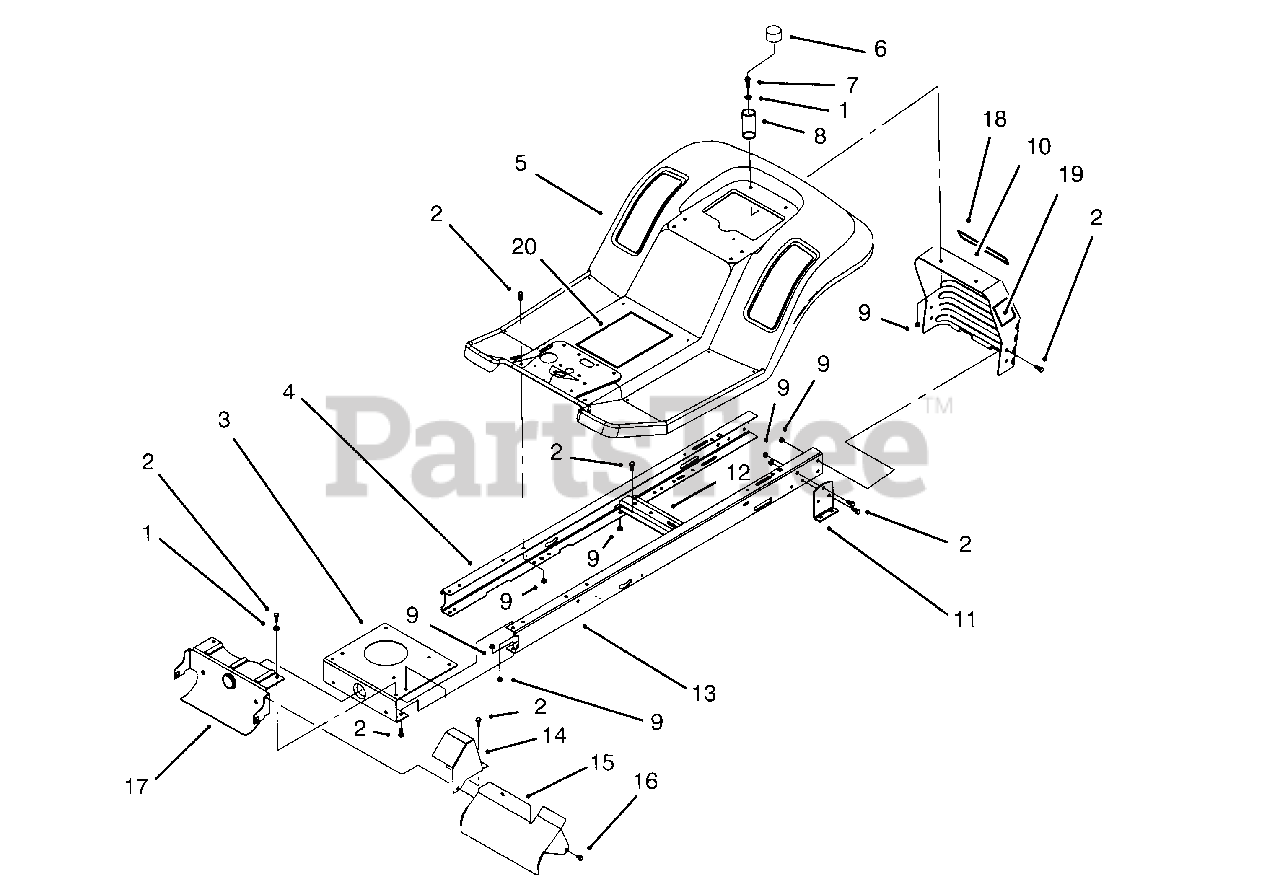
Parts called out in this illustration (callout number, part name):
1	Washer-Flat
2	Screw-Hex Hd. Cap
3	Plate-Engine Mount
4	Rail-R.H. Frame
6	Cap-Protector
7	Screw-Hex Hd. Cap
8	Spring-Compression
9	Nut-Lock
10	Panel-Rear Hitch
11	Bracket-Transaxle Mnt.
12	Bracket-Idler Pivot
13	Rail-L.H. Frame
14	Shield-Exhaust Pipe
15	Shield-Muffler
16	Screw-Thread Tapping
17	Support-Front Axle
18	Decal-Rear Body
19	Decal-Dump Valve Hydro(Model No. 81191 Only)
20	Decal-Instruction(Model No. 81182 & 81180 Only)
